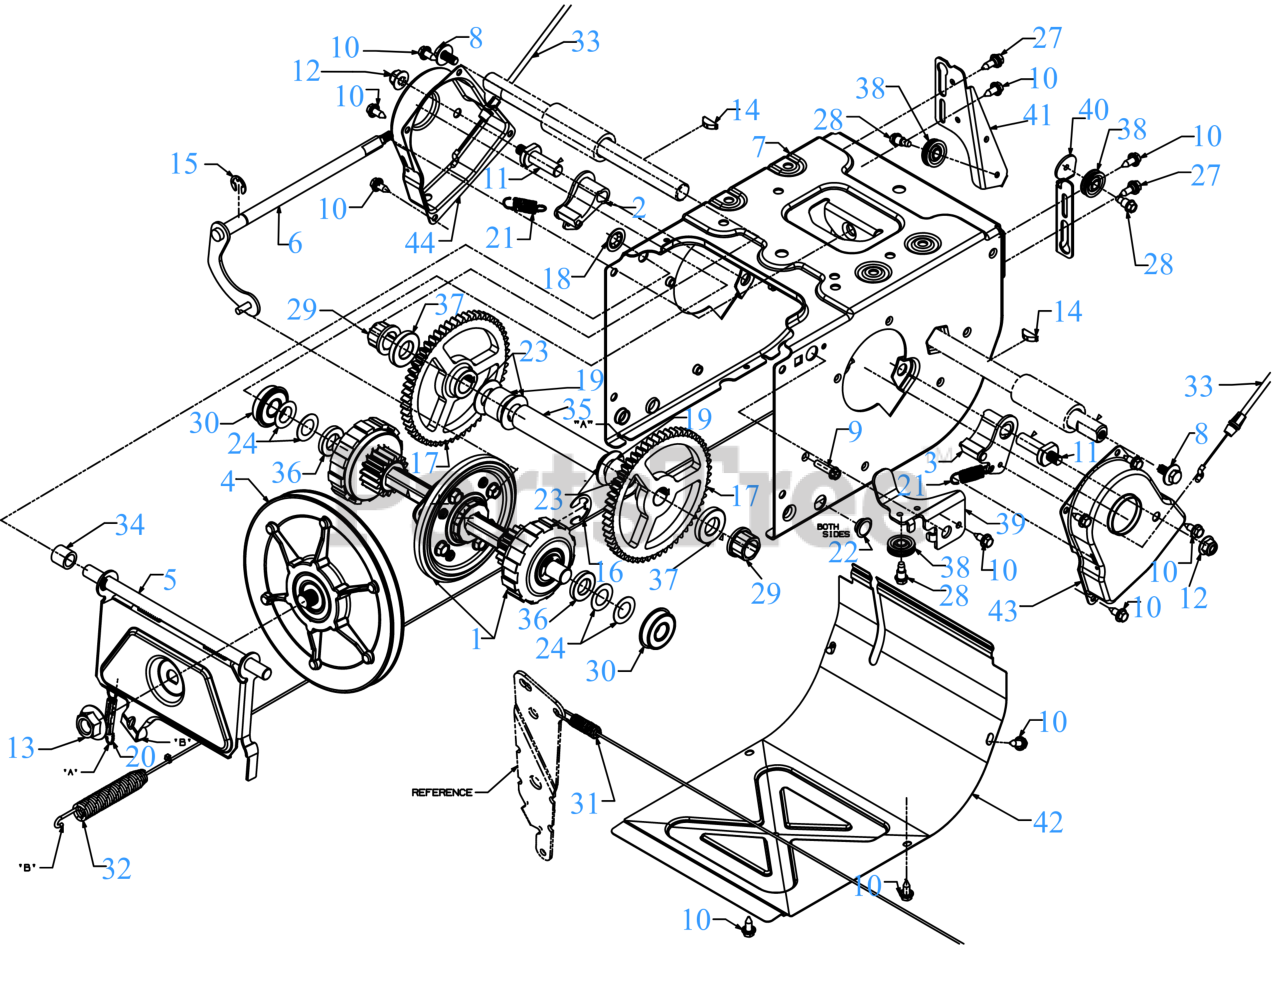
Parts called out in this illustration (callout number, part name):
1	PLANETARY FRICTION WHEEL HEX SHAFT
1	CARRIER ASSEMBLY
1	FRICTION WHEEL ASSEMBLY
2	DOGG ASSEMBLY (RH)
3	DOGG ASSEMBLY (LH)
4	FRICTION WHEEL DISC ASSEMBLY
5	FRICTION WHEEL BRACKET (POWDER BLACK)
6	SHIFT ROD ASSEMBLY
7	DRIVE FRAME HOUSING
8	SCREW 5/16-24 x .750 GR5
9	SCREW 1/4-20 x 1.00
10	SCREW 1/4-20X.625
11	ACTUATOR SHAFT
13	FLANGE NUT 5/8-18
14	KEY 3/16 x 3/4
15	E-RING FOR .500 SHAFT
16	RETAINING RING
19	SPACER: .76ID x .75
20	EXTENSION SPRING
21	EXTENSION SPRING
23	FLAT WASHER .760ID X1.49OD x .06
24	FLAT WASHER .67X 1.174X .02
27	SHOULDER SCREW
28	SHOULDER SCREW
29	FLANGE BEARING
30	BALL BEARING W/RET
31	AUGER DRIVE CABLE 47.48"
32	WHEEL DRIVE CABLE 44.955"
33	STEERING CABLE
34	SPACER-.513 ID x .703 OD x .69
35	AXLE SUPPORT TUBE
37	AXLE SPACER
38	CABLE GUIDE ROLLER
39	AUGER CABLE BRACKET (POWDER BLACK)
40	AUGER CABLE GUIDE BRACKET
41	GUIDE BRACKET
